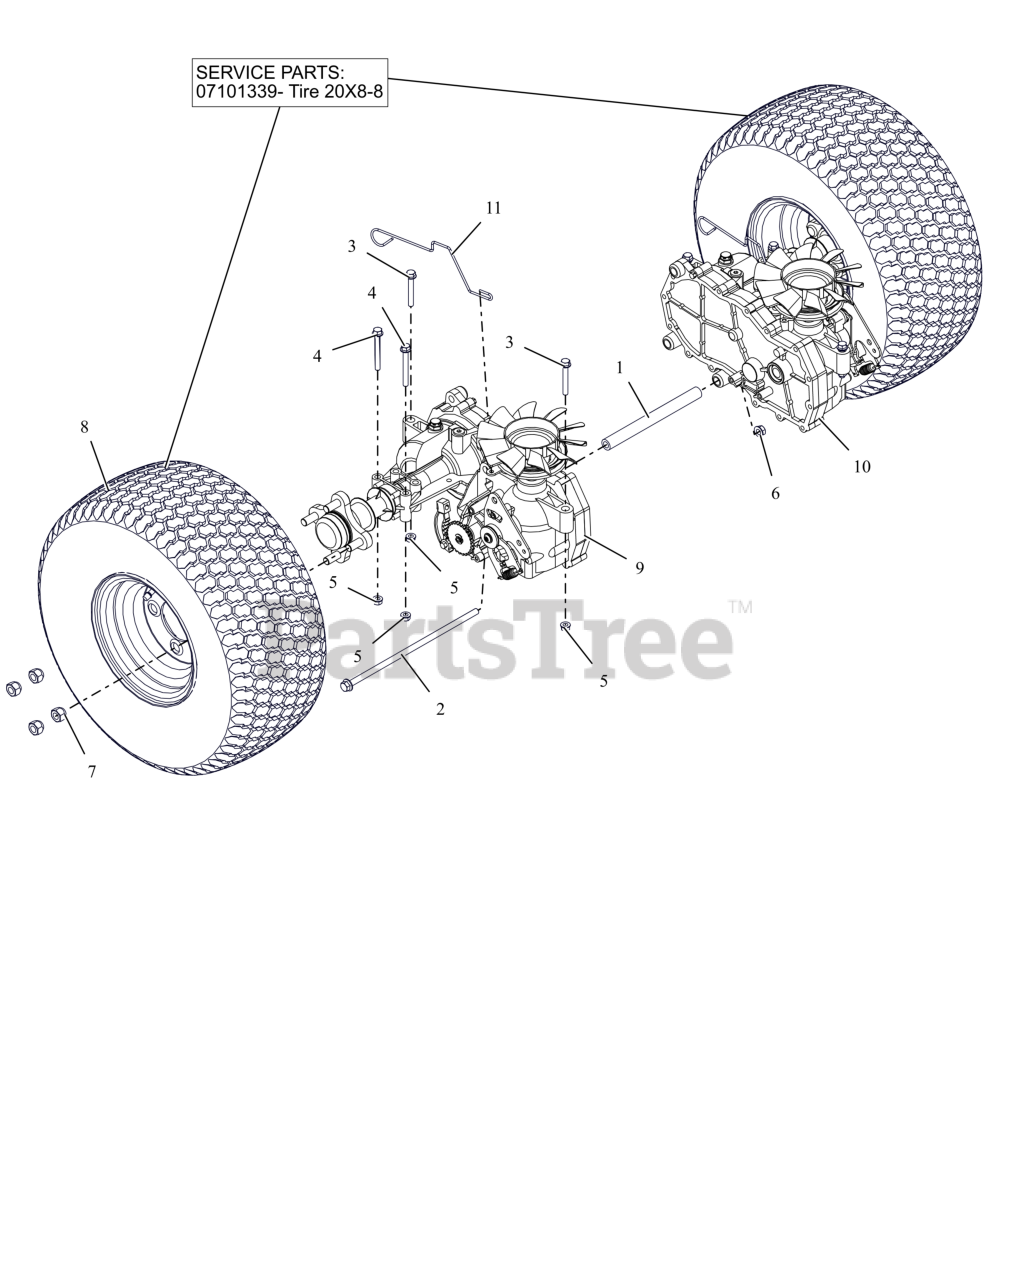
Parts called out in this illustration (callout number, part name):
1	TUBE, TRANSAXLE BRACE 8.18LG
2	BLT,HEX-FLG .38-16X11.5 G5 ZCC
3	BLT,HEX-FLG .31-18X2.25 G5 ZCC
4	BLT,HEX-FLG .31-18X2.75 G5 ZCC
5	NUT,LK-CTR-FLG .31-18 GF ZCC
6	NUT-LK-CTR-FLG .375-16 GF ZCC
7	NUT, WHEEL .50-20 ZCC
8	ASSM TIRE\WHEEL, 20 X 8 -8
8	LAWN TIRE REAR, 4 PLY K505 20/8.00-8
9	TRANSAXLE- EZT-RH
10	TRANSAXLE- EZT - LH
11	WIRE- DUMP VALVE LEVER
